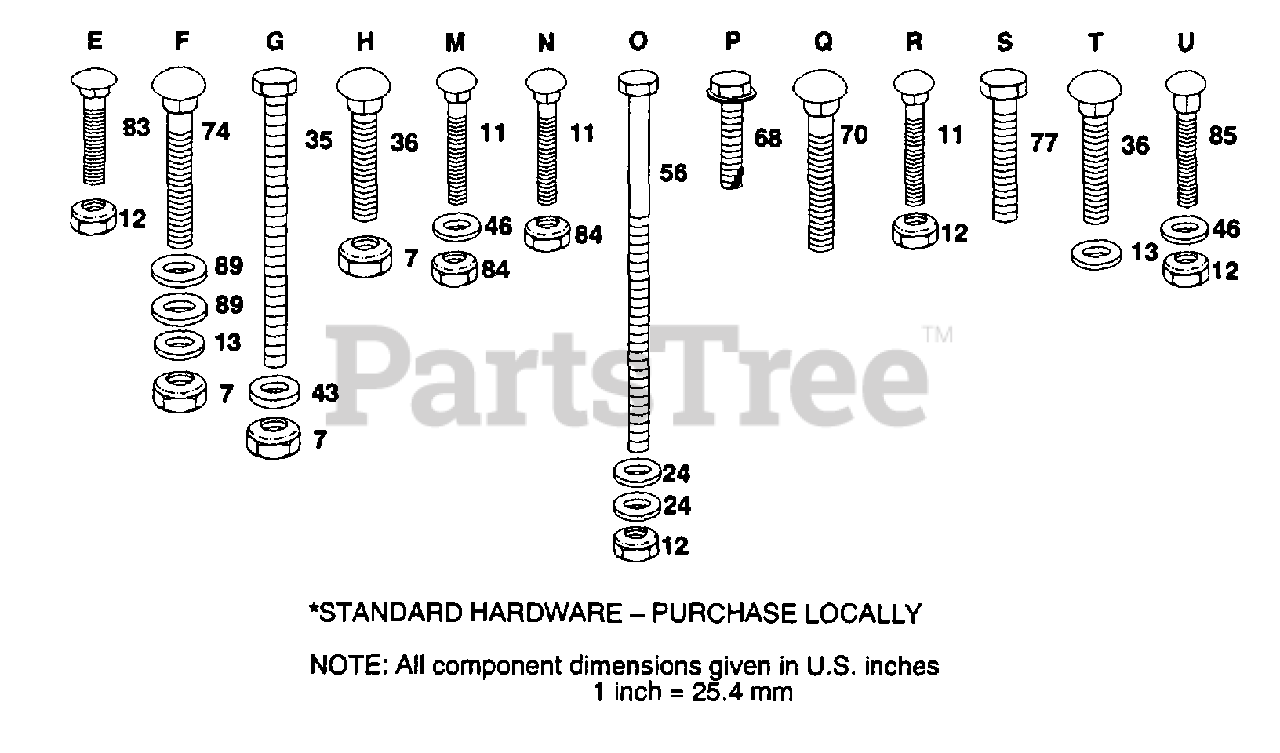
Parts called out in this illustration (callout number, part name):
11	BOLT
13	WASHER
24	WASHER M
35	BOLT - HEX 3/8 - 16 X 3
43	WASHER
46	WASHER
56	BOLT
68	SCREW
70	BOLT
74	BOLT
77	BOLT
83	BOLT
89	WASHER
